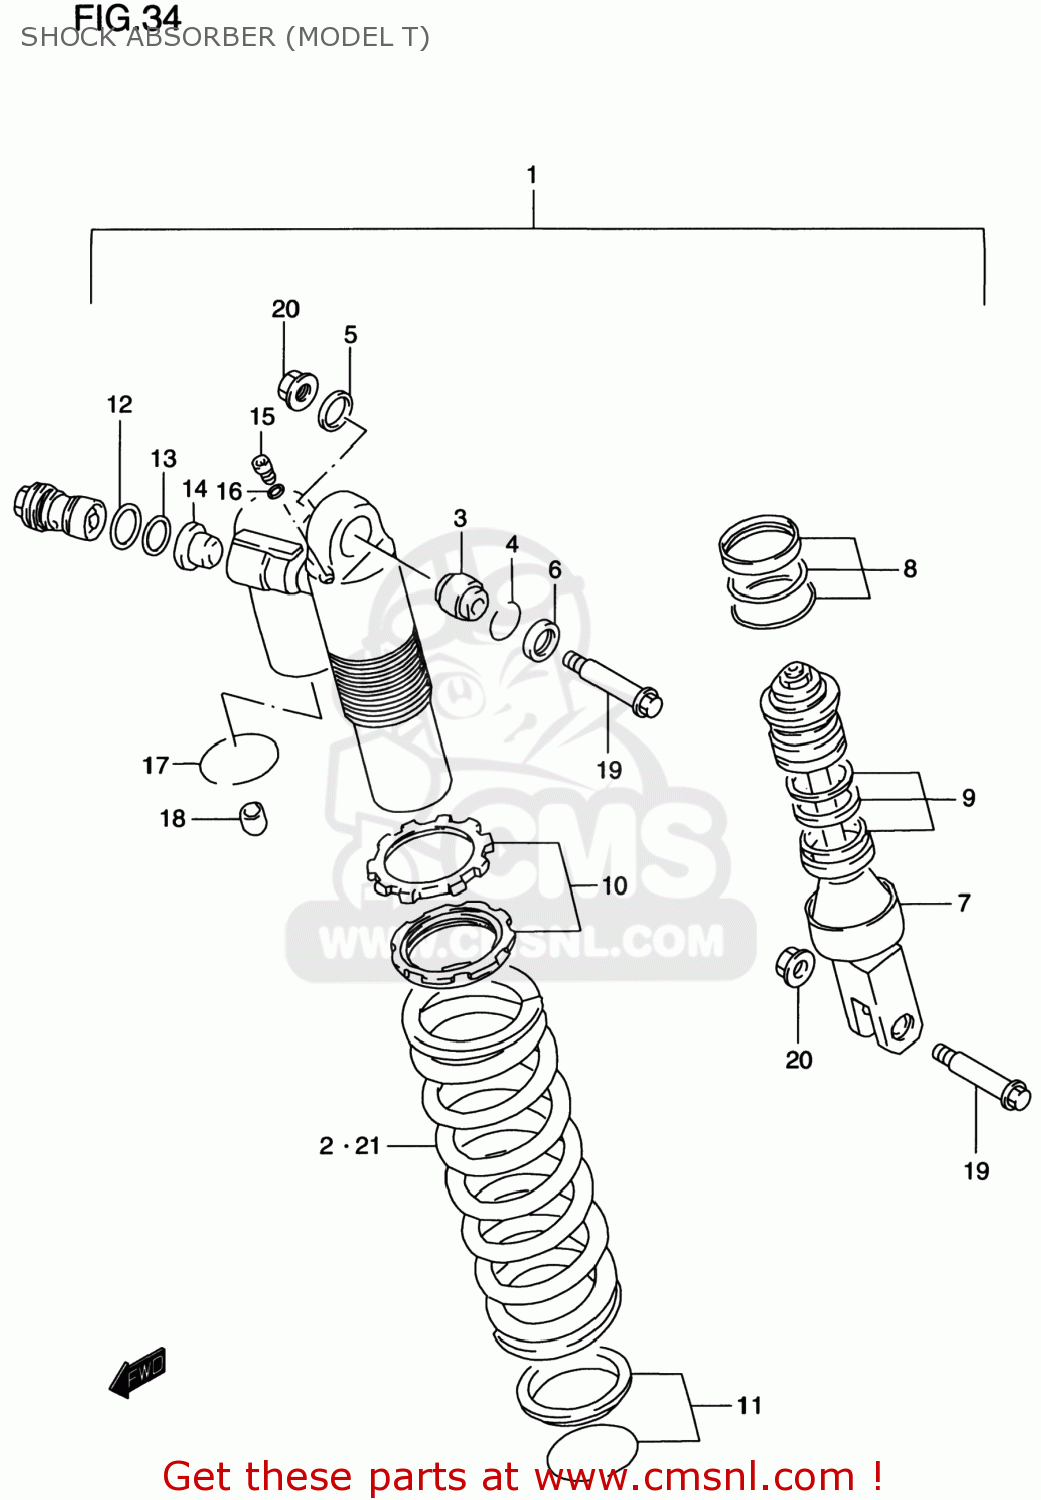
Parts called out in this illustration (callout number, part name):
1	ABSORBER ASSEMBLY,REAR SHOCK
2	SPRING,RR(K=4.8)
3	BEARING,RR SHOCK ABSORBER
4	RING,STOPPER
5	SEAL,DUST UPR,R
6	SEAL,DUST UPR,L
7	ROD,PISTON
8	O RINR SET
9	RING STOPPER SET,ABSORBER
10	ADJUSTER SET,SHOCK ABSORBER
11	SPRING SEAT SET,SHOCK ABSORBER
12	O RING
13	O RING,CTR BOLT UPR
14	COLLAR,ORIFICE
15	BOLT
16	GASKET,DRAIN,PLUG (NAS)
17	RING,STOPPER
18	CAP
19	BOLT(10X47.5)
20	NUT
21	SPRING,RR(K=4.6)
